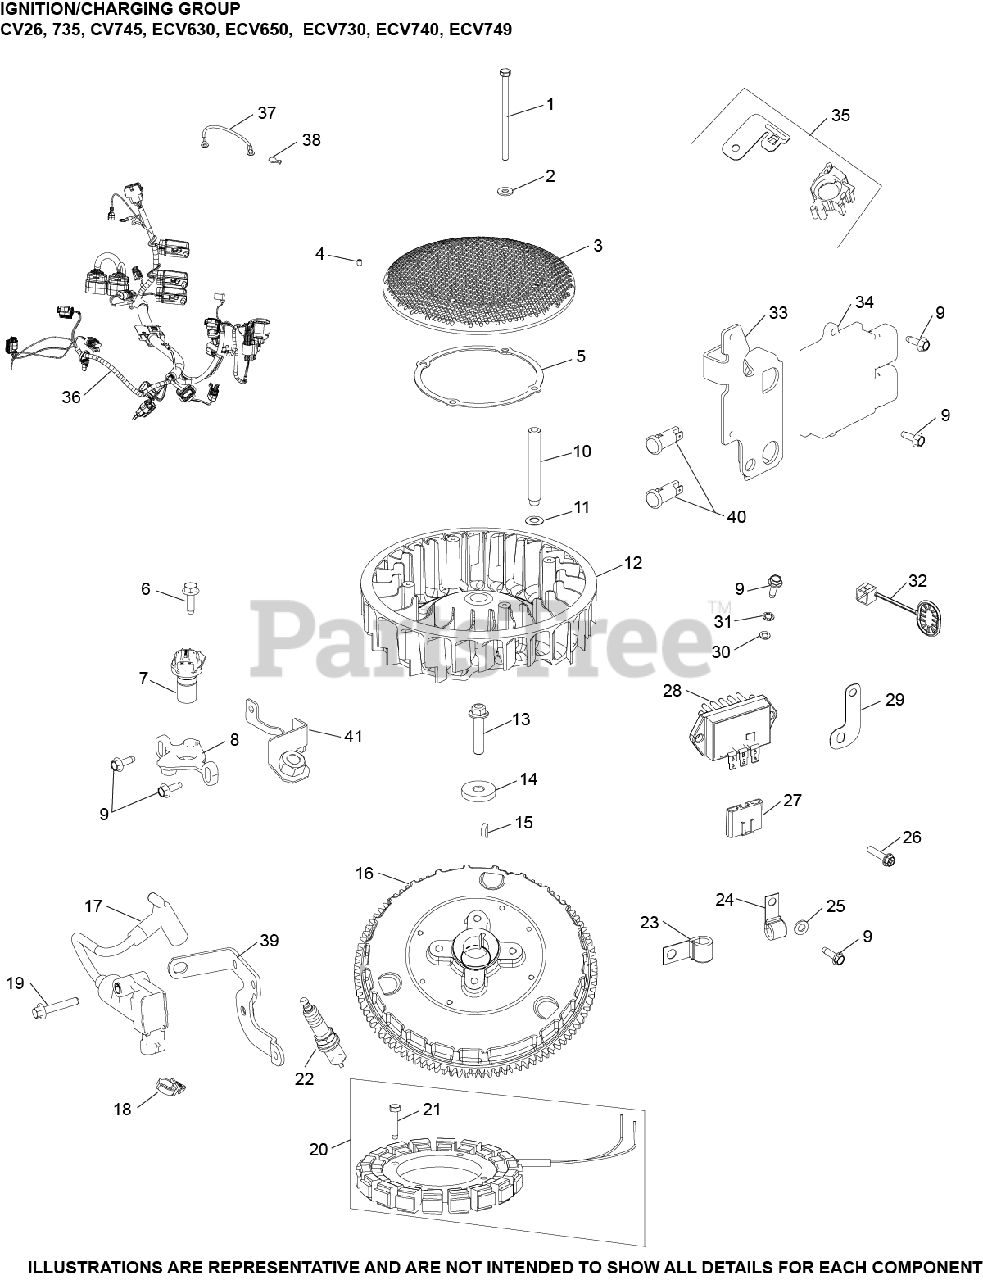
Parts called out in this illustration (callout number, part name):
1	SCREW, CAP M6X1.0X99.5
2	WASHER, FLAT 1/4" (O.D. 5/8")
3	SCREEN, GRASS
4	SCREW, SKT SET #10-24X1/4"
5	RING, SUPPORT USE 25 141 08-S
6	SCREW, THREAD FORMING
7	SENSOR, SPEED
8	BRACKET, SENSOR MOUNT-(#2512616S)
9	SCREW,FLG THD FRM M5X0.8X16-(#25086398S)
11	WASHER, SPRING 10 MM
13	SCREW, FLG M10X1.5X45 - (#25086361S)
14	WASHER, FLAT 13/32"
15	KEY, 3/16" X 5/8"
16	FLYWHEEL ASSEMBLY
17	COIL, IGNITION-EFI - USE 25 519 02-S
19	SCREW, FLG M6X1.0X34
20	KIT, 15 / 20 AMP STATOR
21	SCREW, M5X0.8X25 - (#25086402S)
22	SPARK PLUG, RFI
24	CLIP, CABLE
25	WASHER, FLAT 1/4" (O.D. 1/2")
26	SCREW, HEX FLANGE HI-LO
27	CONNECTOR
28	REGULATOR, RECTIFIER USE 25 403 32-S
29	BRACKET, GROUND STRAP USE 24 518 12-S
30	WASHER, FLAT 3/16"
31	WASHER, INT TOOTH LOCK #10
32	CAP, CONNECTOR
33	BRACKET, ECU
34	MODULE, ECU ECV650 USE 24 584 185-S
35	KIT, MOUNTING CLIP
36	HARNESS, WIRING ASSEMBLY
